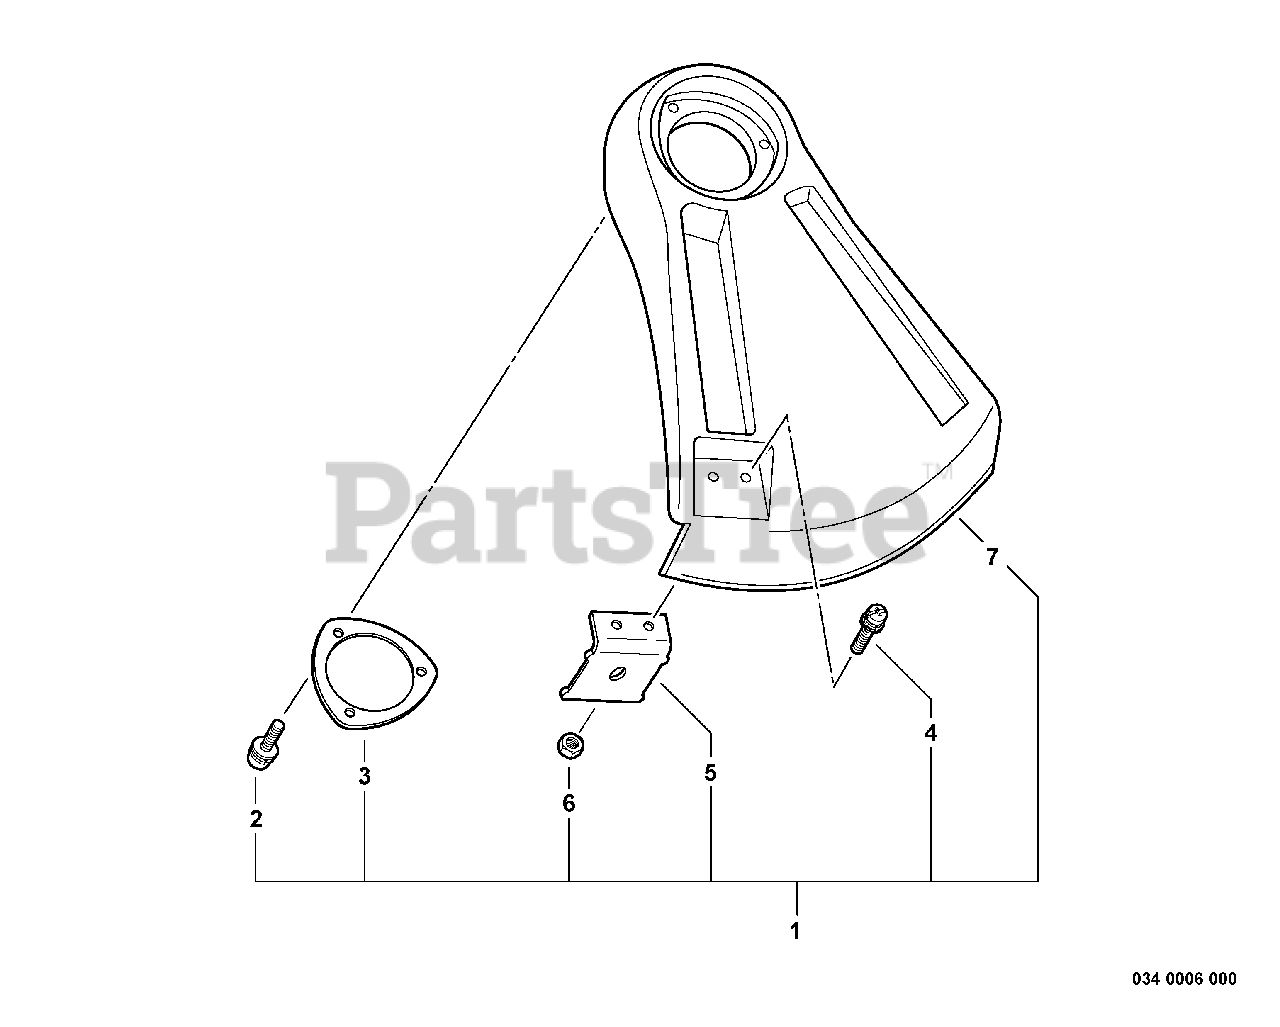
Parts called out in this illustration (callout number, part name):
1	DEBRIS SHIELD KIT
2	SCREW 5×16
3	PLATE, SHIELD Ø49.5 MM
4	SCREW 5×16
5	CUTTER, LINE
6	NUT M5
7	SHIELD, DEBRIS PLASTIC
